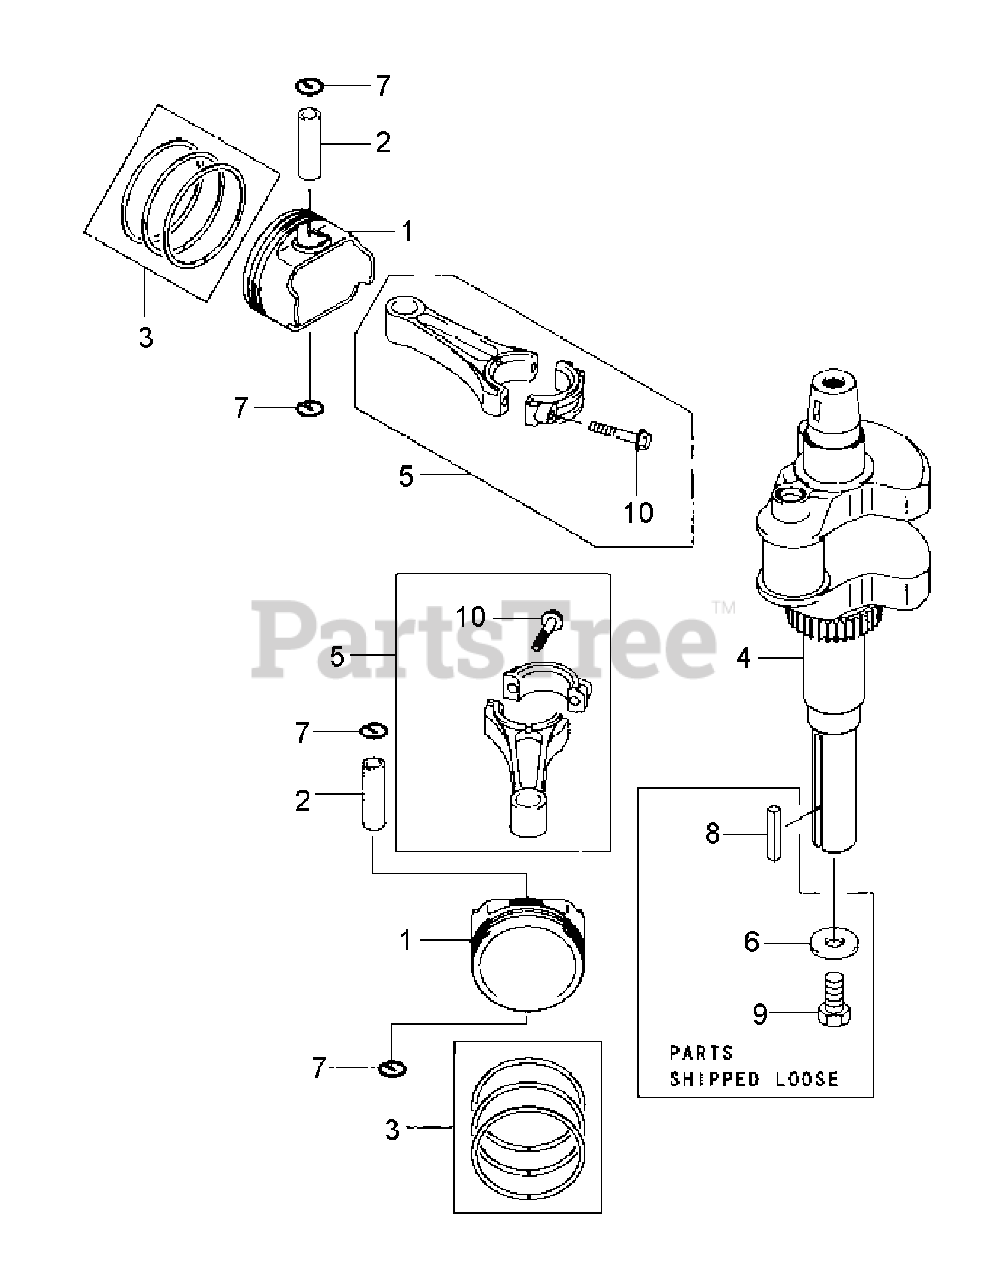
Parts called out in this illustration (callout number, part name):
1	PISTON-ENGINE
1	PISTON-ENGINE .50
3	RING-SET-PISTON
3	RING-SET-PISTON .50
4	CRANKSHAFT-COMP
5	ROD-ASSY-CONNECTING
6	WASHER 12.5x32x3.2
9	BOLT 7/16" x 20
10	BOLT, 6x35
